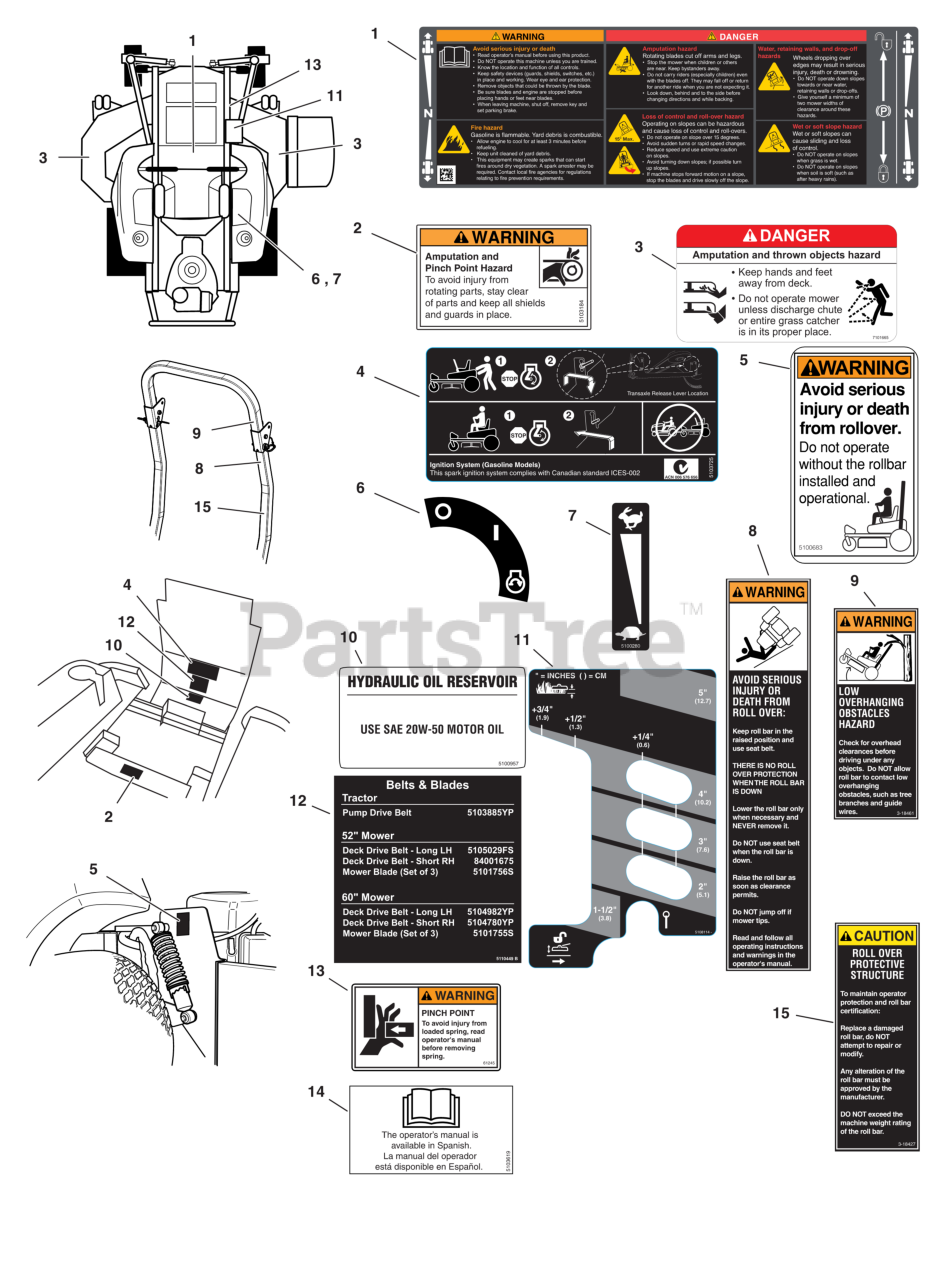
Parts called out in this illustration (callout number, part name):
1	DECAL, MAIN SAFETY
2	DECAL, WARNING, ENG
3	DECAL, DANGER
4	DECAL, TRANS RELEASE
5	DECAL, WARNING
6	DECAL, IGNITION SWITC
7	DECAL, THROTTLE CONTR
8	DECAL, WARNING, ROPS
9	DECAL, WARNING OVERHA
11	DECAL, CUTTING HEIGHT
12	DECAL, Belt & Blade
13	DECAL, PINCH POINT
14	DECAL, MANUAL
15	DECAL, CAUTION, ROPS
